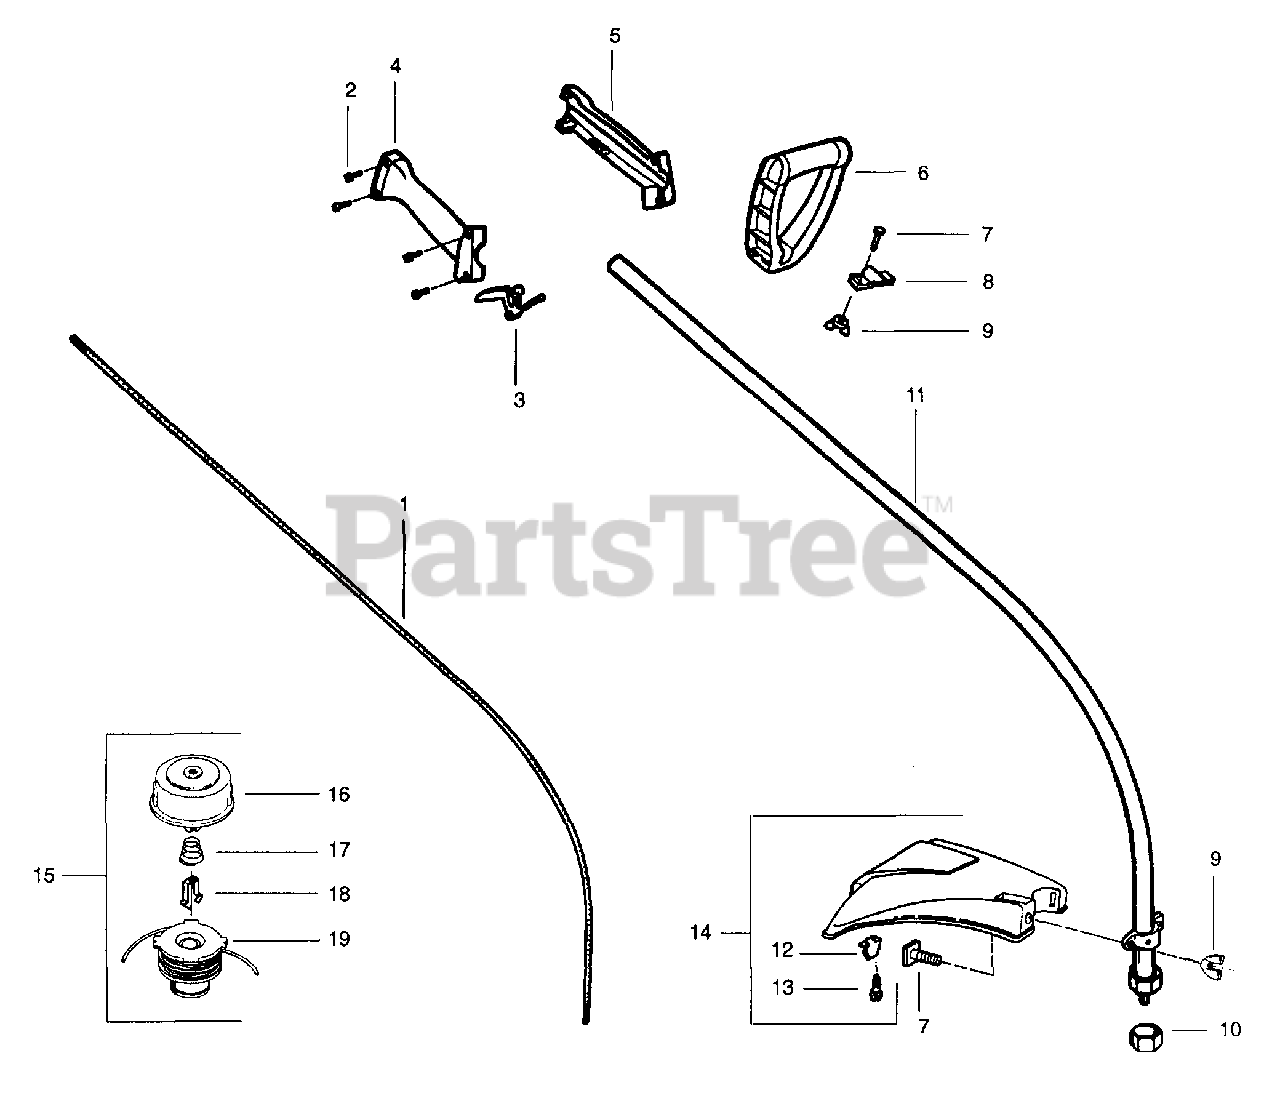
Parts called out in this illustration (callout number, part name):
1	Drive Shaft
2	Screw-Throttle Hsg.
4	Throttle Hsg. (Right)
5	Throttle Hsg. (Left)
6	Handle Ass'y.
7	Bolt - Handle/Shield
8	Clamp - Assist Handle
9	Wingnut
10	Dust Cup
11	Drive Shaft Hsg. Ass'y.
12	Line Limiter
13	Screw-Line Limiter
14	Shield Kit Ass'y.
15	Cutting Head Ass'y.
16	Hub Ass'y.
17	Spring - Return
18	Retainer - Spool
19	Spool w/Line
